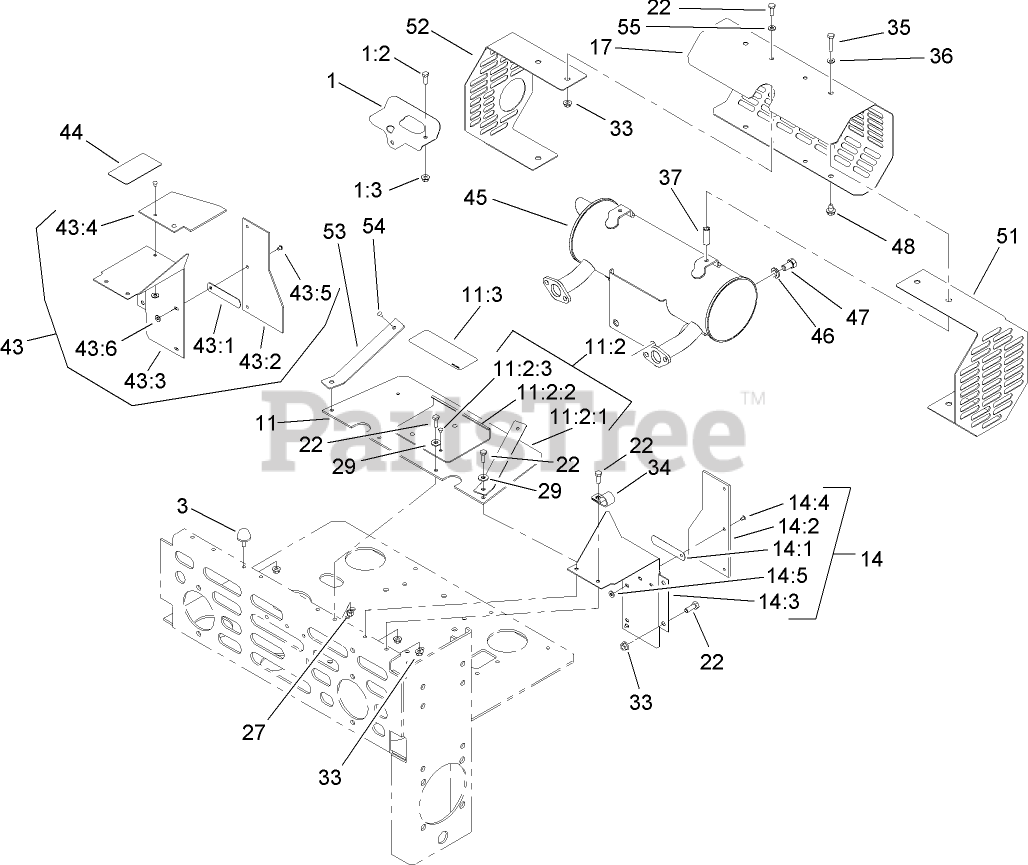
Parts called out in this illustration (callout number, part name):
1	Cable Heat Shield Kit
1:2	SCREW-HH
1:3	NUT-HF
3	BUMPER
11	SHIELD ASM
11:2	SHIELD AND LIFT ASM
11:2:1	SHIELD-ENGINE
11:2:2	LIFT-SHIELD
11:2:3	RIVET-POP
11:3	DECAL-DEVICES, ROTATING
14	LH SHIELD ASM
14:1	CLIP-BAFFLE, REAR
14:2	SHIELD-ENGINE
14:3	BAFFLE-ENGINE SHIELD, LH
14:4	RIVET-POP
14:5	WASHER-FLAT
17	GUARD-MUFFLER
22	SCREW-HH
27	NUT-LOCK, NI
29	WASHER-FLAT
33	NUT-HF
34	CLIP-LOOM
36	WASHER-SPRING
37	SPACER
43	RH SHIELD ASM
43:1	CLIP-BAFFLE, REAR
43:2	SHIELD-ENGINE
43:3	SHIELD-RH
43:4	BAFFLE-COOLER, ENGINE
43:5	RIVET-POP
43:6	WASHER-FLAT
44	DECAL-ROUTING, BELT
45	MUFFLER
46	WASHER-LOCK
47	SCREW-HH
48	SCREW
51	SHIELD-MUFFLER, LH
52	SHIELD-MUFFLER, RH (CE)
53	SHIELD STRAP
54	RIVET-POP
55	WASHER-FLAT
